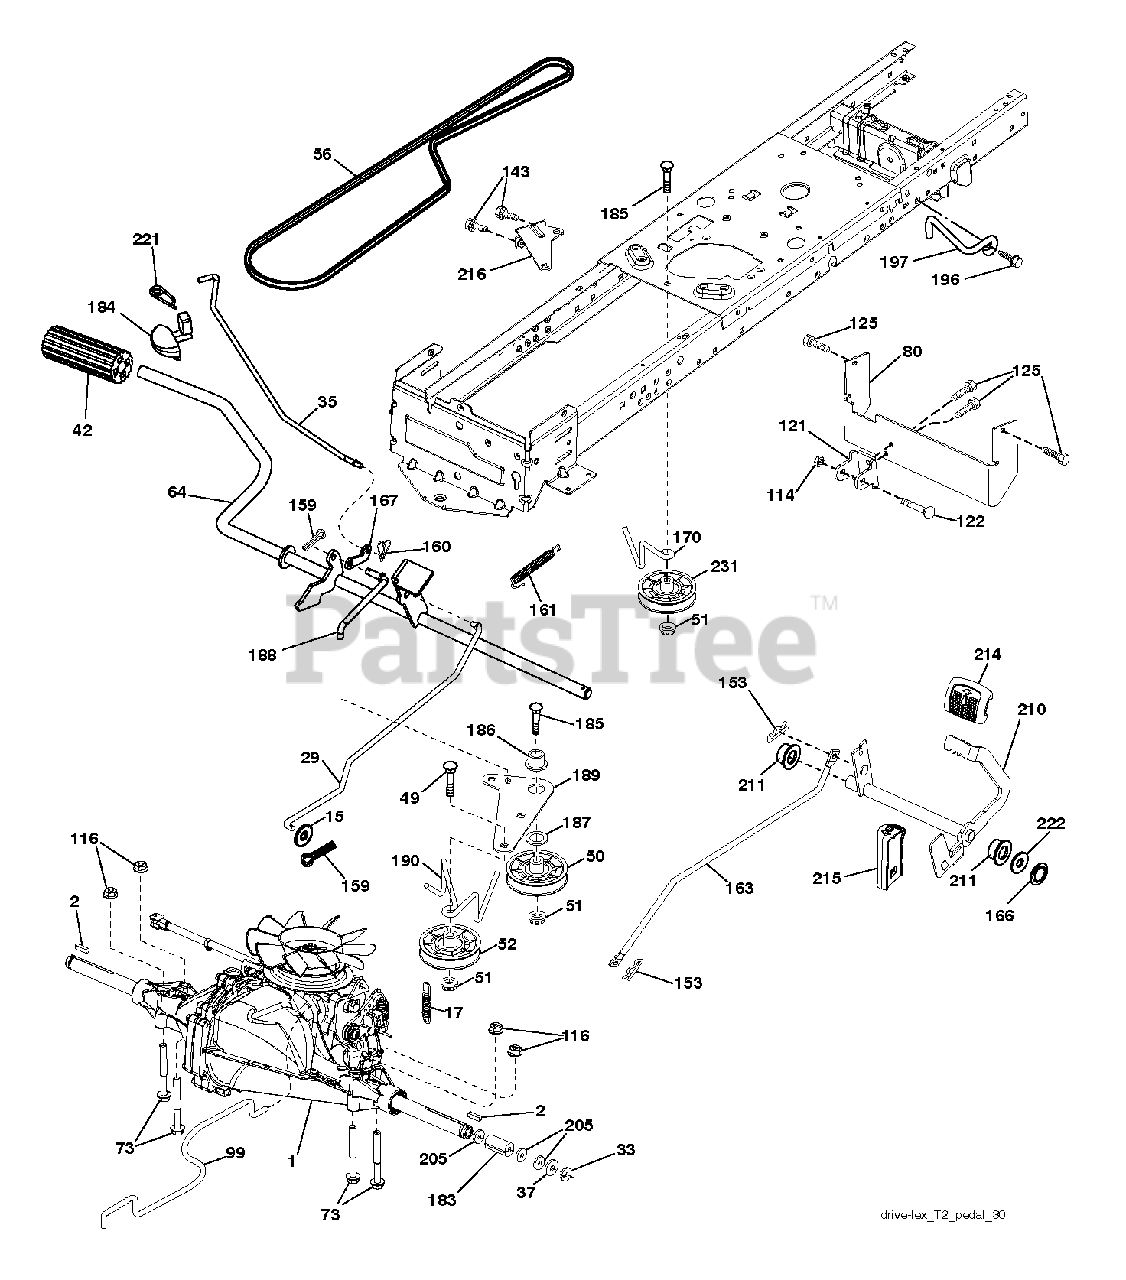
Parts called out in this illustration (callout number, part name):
2	SQUARE KEY
15	WASHER
17	SPRING.BRAKE.HG3000/3500
29	ROD.BRAKE.T2.TEX
35	ROD.CNTRL.PARK.PREDATOR.LT.TEX
42	PEDAL COVER T
50	IDLER.FLAT.910.OFFSET
51	NUT LOCK FLG 3/8-16 UNC
52	IDLER.V-GROOVE.910.OFFSET
64	SHAFT.ASM.PEDAL.BRK.CNTR
73	BOLT HEX 5/16-18 GR 5
80	STRAP.TORQUE.T2
99	ROD.ASM.BYPASS.SPRING.T2.FS
114	NUT.71038.31-18.HEX.NYLOCK
116	NUT LOCK HEX FLANGE 5/16-18
121	BRACKET STRAP TORQUE
122	BOLT.5/16-18X2.5
125	SCREW
143	SCREW LT
153	RETAINER M
159	COTTER PIN
160	RETAINER CLIP
161	SPRING, RETURN LT
163	ROD.CONTROL.PCH.T2.TEX
166	NUT.PUSH.625
167	LATCH.BRAKE.SPRING
170	KEEPER.CENTER SPAN.1.688
183	SPACER, AXLE PVST
184	HANDLE.PARKING.BRK.PRED.LT.RED
186	SPACER.RETAINER
187	WASHER 12/32X2X10GA
188	RP LINK.CLUTCH.GROUND.DRIVE
189	BELLCRANK.GROUND.DRIVE.TEX.
190	KEEPER.BELLCRANK.DRIVE
196	SCREW 3/8-16X1
197	LINK.CLUTCH.ANIT-ROTAT
210	ROCKER.ASM.PEDAL.CONTR
211	BEARING.NYLON
214	PEDAL.FORWARD.PAD.TEX
215	PEDAL RUBBER REVERSE
216	BRACKET.PULLEY.IDLER.W/TEX
221	RETAINER.SPRING.CLIP.H
222	WASHER 21/32 X 1-1/4 X 10 GA.
231	IDLER.V-GROOVE.1.688.OFFSET
